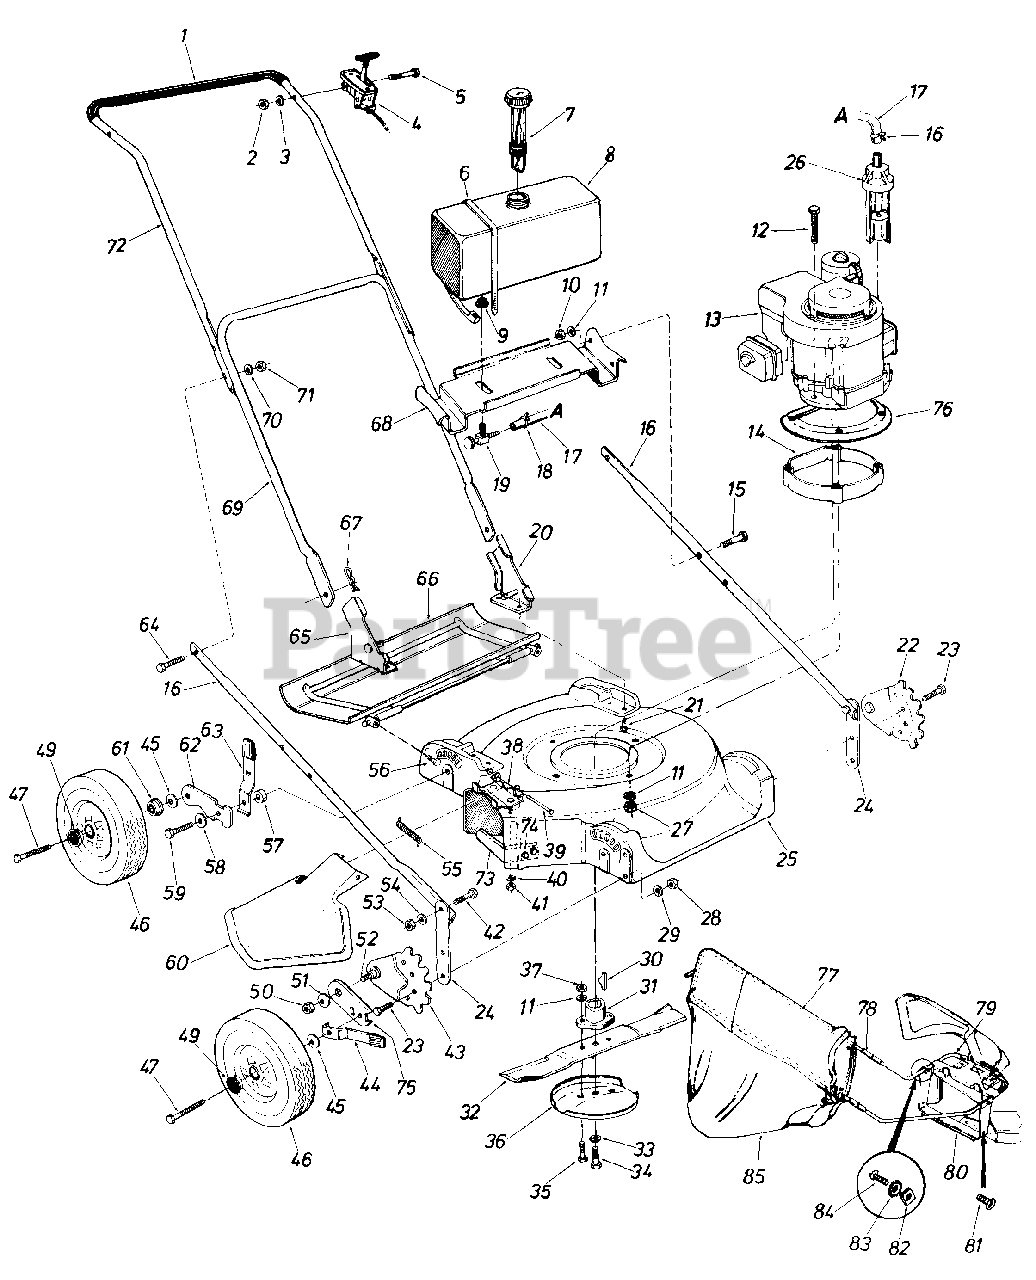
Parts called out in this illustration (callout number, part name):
2	Hex Nut 1/4-20 Thd.
3	L-Wash. 1/4" I.D.
4	Throttle Control Ass'y. Comp.
5	Hex Bolt 1/4-20 x 1.50" Lg.
6	Cable Tie
7	Fuel Gauge
8	Fuel Tank
9	Bushing
10	Hex Cent. L-Nut 5/16-18 Thd.
11	L-Wash. 5/16" I.D.
12	Hex Bolt 5/16-24 x 2.75" Lg.
13	Engine
14	Spacer Ass'y.
15	Hex Bolt 5/16-18 x 1.50" Lg.
17	Fuel Line - 12" Long
18	Hose Clamp 3/8" I.D.
19	Fuel Shutoff Valve
20	Handle Mount Bracket
21	Hex Wash. Hd. Self-Tap Scr. 5/16-18 x .50" Lg.
22	Height Adjuster Ass'y. - L.H.
23	Hex Bolt 3/8-16 x 1.00" Lg.
24	Strut Mount Bracket
25	20" Deck
26	Fuel Control Valve
27	Hex Nut 5/16-24 Thd.
28	Hex Nut 3/8-16 Thd.
29	L-Wash. 3/8" I.D.
30	#6 Hi-Pro Key 5/32 x 5/8" Dia.
31	Blade Adapter Kit
32	20" Blade
33	L-Wash. 3/8" I.D. Heavy Duty
34	Hex Bolt 3/8-24 x 1.50" Lg. (Grade 5)
35	Hex Bolt 5/16-24 x 1.00" Lg. (Grade 5)
36	Scalp Plate
37	Hex Nut 5/16-24 Thd.
38	Adapter Plate Ass'y.
39	Pivot Pin
40	L-Wash. 1/4" I.D.
41	Hex Nut 1/4-28 Thd.
42	Hex Bolt 5/16-18 x .75" Lg.
43	Height Adjuster Ass'y. - R.H.
44	Spring Lever Ass'y. w/Knob
45	Belleville Wash. 3/8" I.D.
46	Wheel Ass'y. Comp.
47	Hex Bolt 3/8-16 x 1.75" Lg.
49	Flanged Ball Brg.
50	Hex Cent. L-Nut 3/8-16 Thd.
51	Belleville Wash.
52	Shoulder Bolt 3/8-16 Thd.
53	Hex Cent. L-Nut 5/16-18 Thd.
54	L-Wash. 5/16" I.D.
55	Torsion Spring
56	Hex Bolt 1/4-28 x .62" Lg.
57	Shoulder Spacer
58	Belleville Wash.
59	Hex Bolt 3/8-24 x 1.50" Lg. H.T.
60	Chute Deflector Ass'y. - Comp.
61	Flanged Ball Bearing
62	Pivot Bar
63	Spring Lever Ass'y. w/Knob
64	Hex Bolt 5/16-18 x 1.75" Lg.
65	Handle Mount Brkt.
66	Rear Shield Ass'y.
67	Hairpin Cotter
68	Fuel Tank Mounting Brkt.
69	Lower Handle
70	L-Wash. 5/16" I.D.
71	Hex Cent. L-Nut 5/16-18 Thd.
72	Upper Handle
73	Internal Bar
74	Hex Bolt 1/4-20 x .75" Lg.
75	Pivot Bar
76	Engine Mount Cover Plate
77	Upper Frame
78	Tubing Connector
79	Lower Frame Ass'y.
80	Lower Frame Bracket
81	Truss Hd. Mach. Scr. #10-24 x .38" Lg.
82	Sq. Nut #10 I.D.
83	Ext. L-Wash. #10 I.D.
84	Truss Hd. Mach. Scr. #10-24 x 1.00" Lg.
85	Grass Bag
